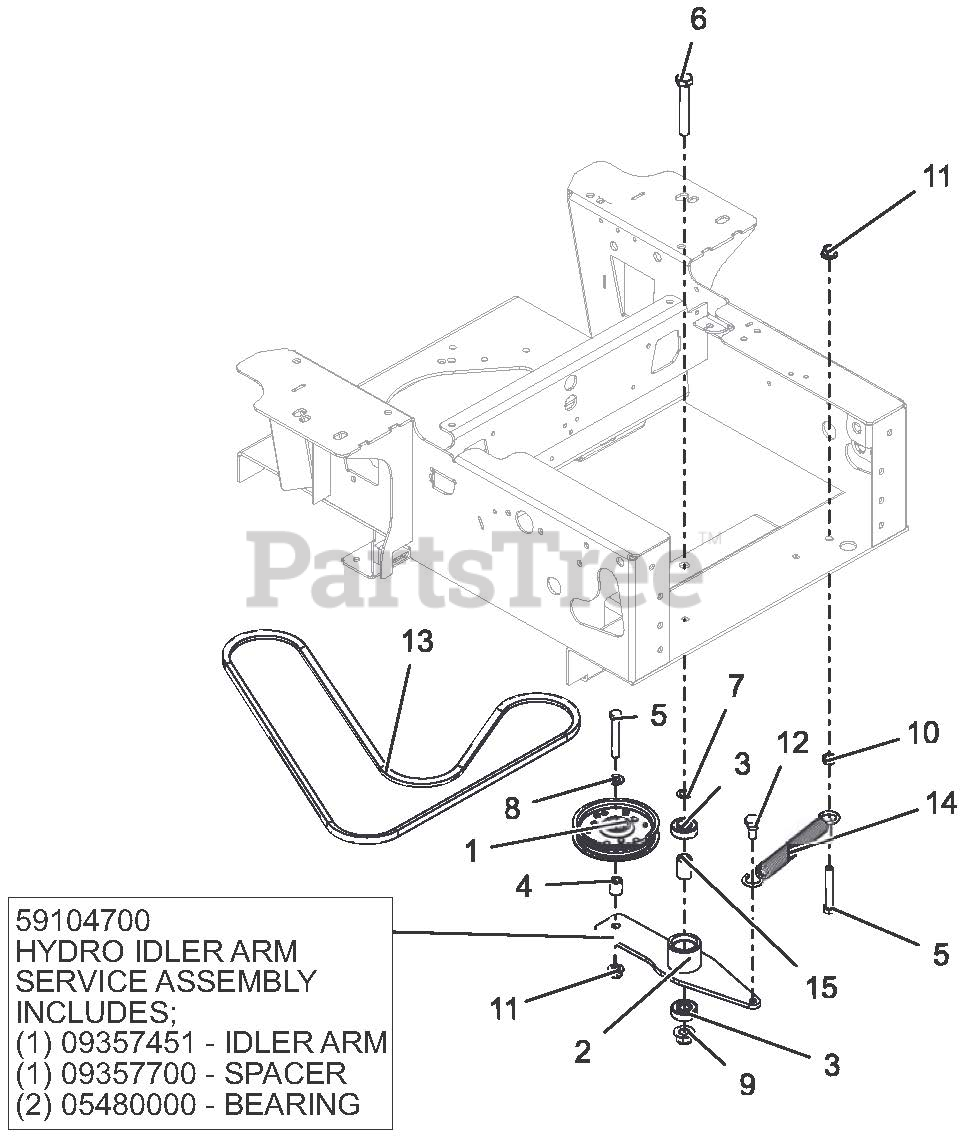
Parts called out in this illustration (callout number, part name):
1	ASM, IDLER 4"
2	WLDMT, HYDRO DRIVE IDLER ARM-BLACK
2	HYDRO IDLER ARM SERVICE ASSEMBLY
2	IDLER ARM
2	SPACER
2	BEARING
3	BRG-BALL .500 X 1.375 X .44
4	BSHG-SLV .407 X ..625 X .750
5	BLT-HEX .38-16 X 2.50 GR5 YWZC
6	BLT-HEX .50-13 X 3.25 GR5 YWZC
7	WASHER-FLAT-STL, .500 X .750 X .020
8	WSHR-FL-STL .406 X .812 X .065 YWZ
9	NUT-LK-NYL-FLG .50-13 YWZC
10	NUT-HEX .38-16 YWZC
11	NUT-LK-NYL-FLG .38-16 YWZC
12	BLT, SHLDR EP .38-16 X .30 HEX YZ
13	BELT, V-A-COGGED
14	SPRG, EXTENSION
15	SPACER, .510 X .750 X 1.148
